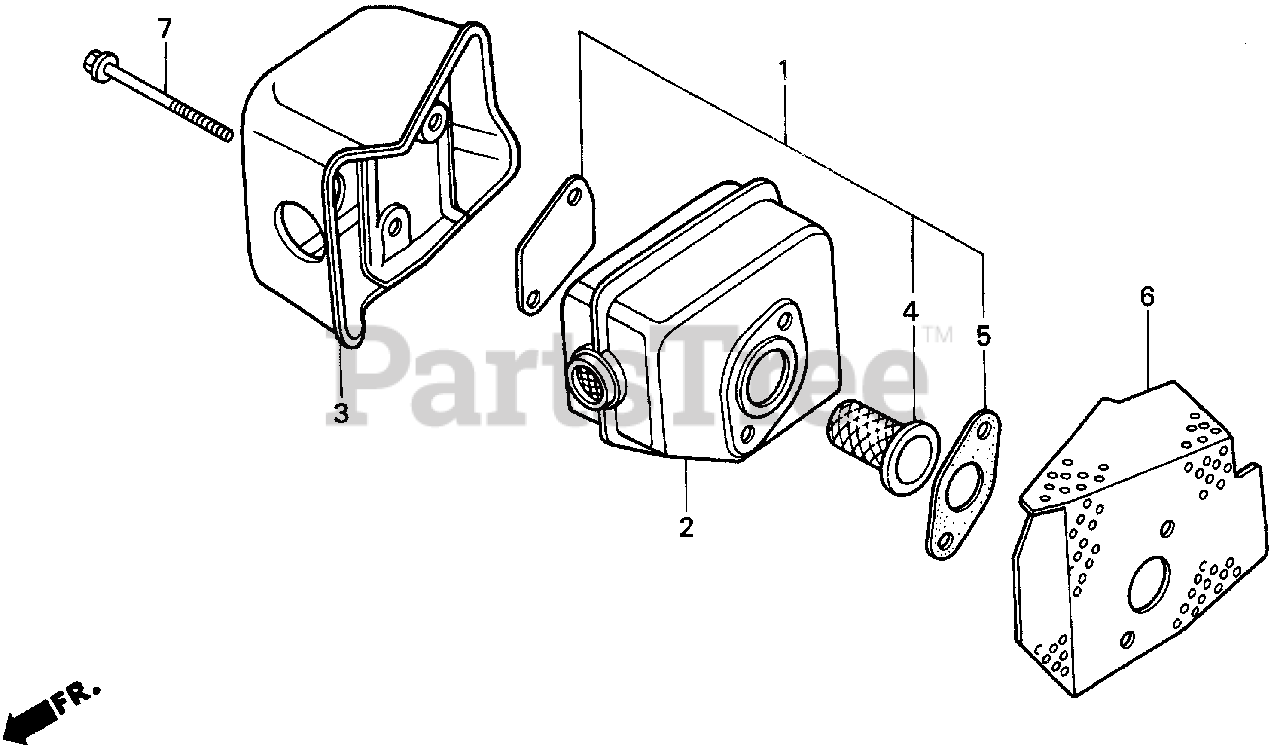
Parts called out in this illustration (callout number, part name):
1	ARRESTER KIT, SPARK
2	MUFFLER
3	PROTECTOR, MUFFLER
4	ARRESTER KIT, SPARK
5	GASKET, MUFFLER
6	GASKET, MUFFLER
7	BOLT, FLANGE (6X85)
